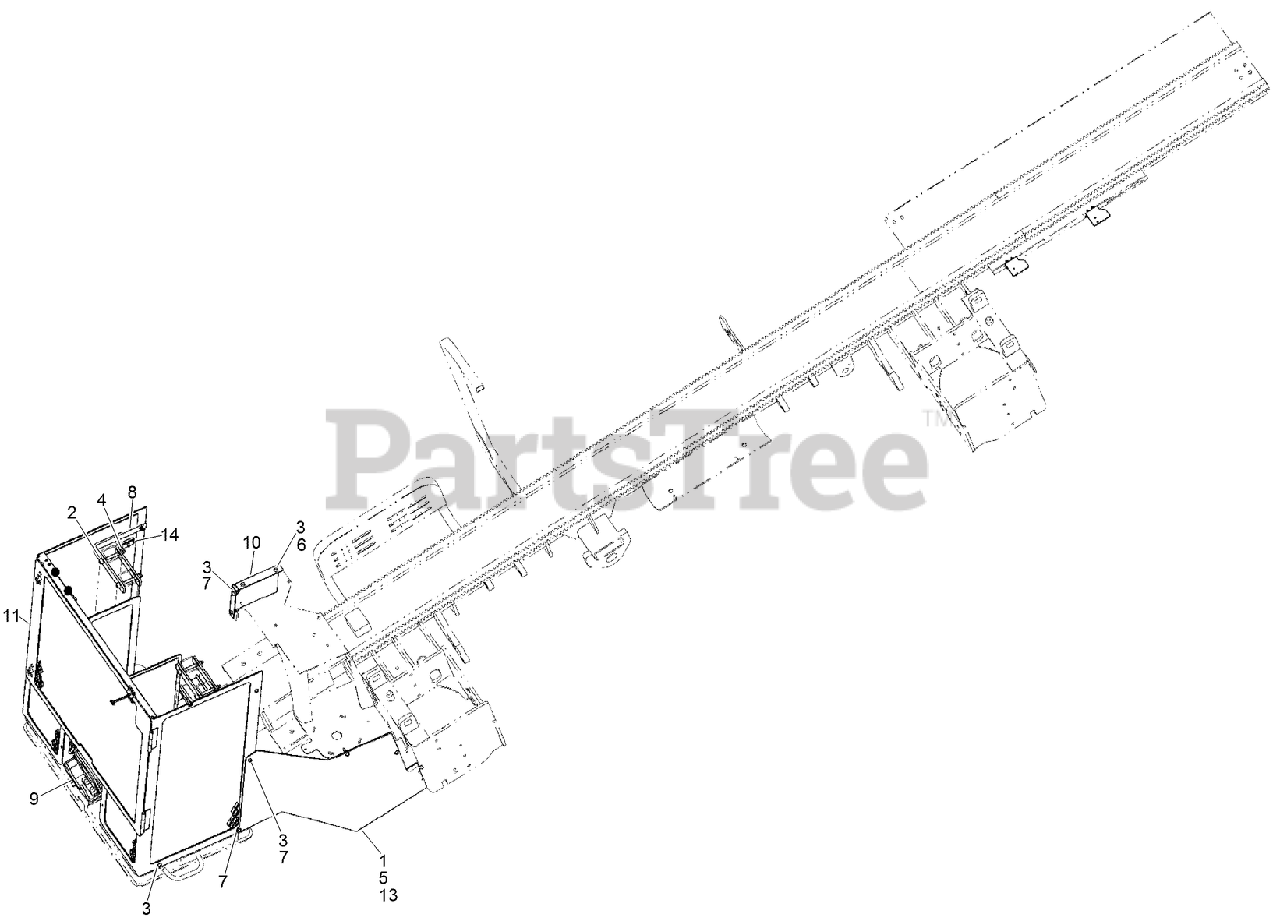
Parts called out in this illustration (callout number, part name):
1	SCREW, METRIC FLANGE w/BODY - M8 x 35
2	SCREW-HHF
3	NUT-TORQUE, PREVAILING
4	NUT-HHF, LOCK
6	SCREW-HH
7	SCREW-HHF
8	PLATE - Stakedown Guard Mounting
9	ASSEMBLY - Rod Guide
10	PLATE - Guard
11	COVER - Stakedown
13	COVER, GUARD - 9 Section Valve
14	ASSEMBLY - Bracket
